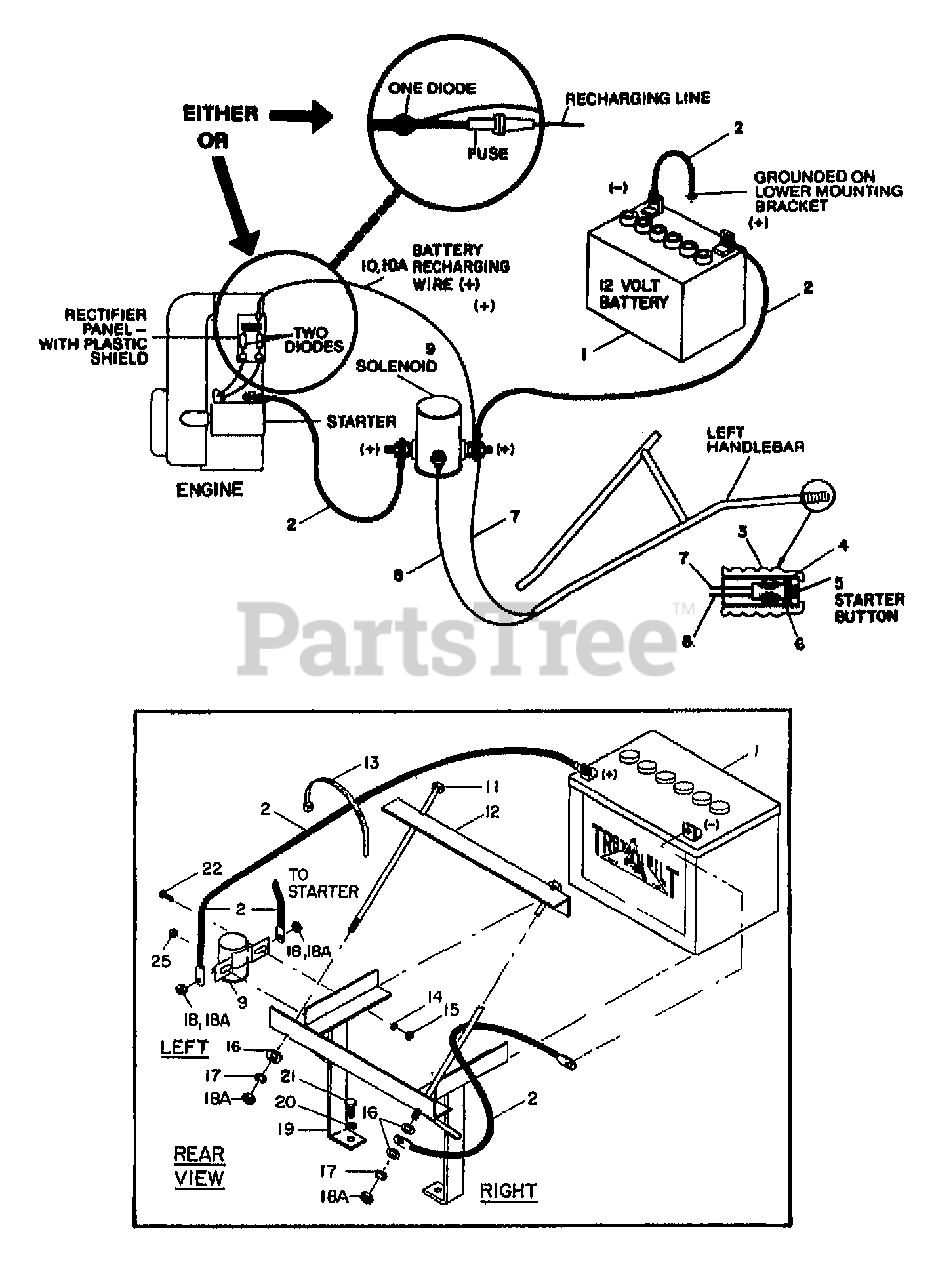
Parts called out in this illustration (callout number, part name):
1	KIT-VENTED BATTERY
2	CABLE-BATTERY
3	GRIP-HANDLEBAR
4	SPACER-1.25X1X1.375
5	SWITCH-STARTER
6	WASHER-#1.25X.938X.062
7	ASSM-WIRE LG
8	ASSM-WIRE SM
9	KIT-SOL W/HDW
10	ASSEMBLY-CONNECTOR
10A	ASSM-WIRE SOL/RECTIFIER
11	SCR-HH 5/16-18 X 9
12	CLAMP-BATTERY BRKT
13	TIE-RED
14	WASHER-LK .25 ZP
15	NUT-HEX 1/4-20 ZP
16	WASHER-FLAT 5/16 SAE
17	WASHER-LK .312 ZP
18	NUT-HEX 5/16-24
18A	NUT-HEX 5/16-18 ZP
19	KIT-BATTERY BRKT HORSE
20	WASHER-LK .375 @ DEPL
21	BOLT-HH 3/8-16X1.5 FTH ZP
22	SCR-RH 1/4-20 X .75 ZP
25	NUT-HH M10-32X.125
